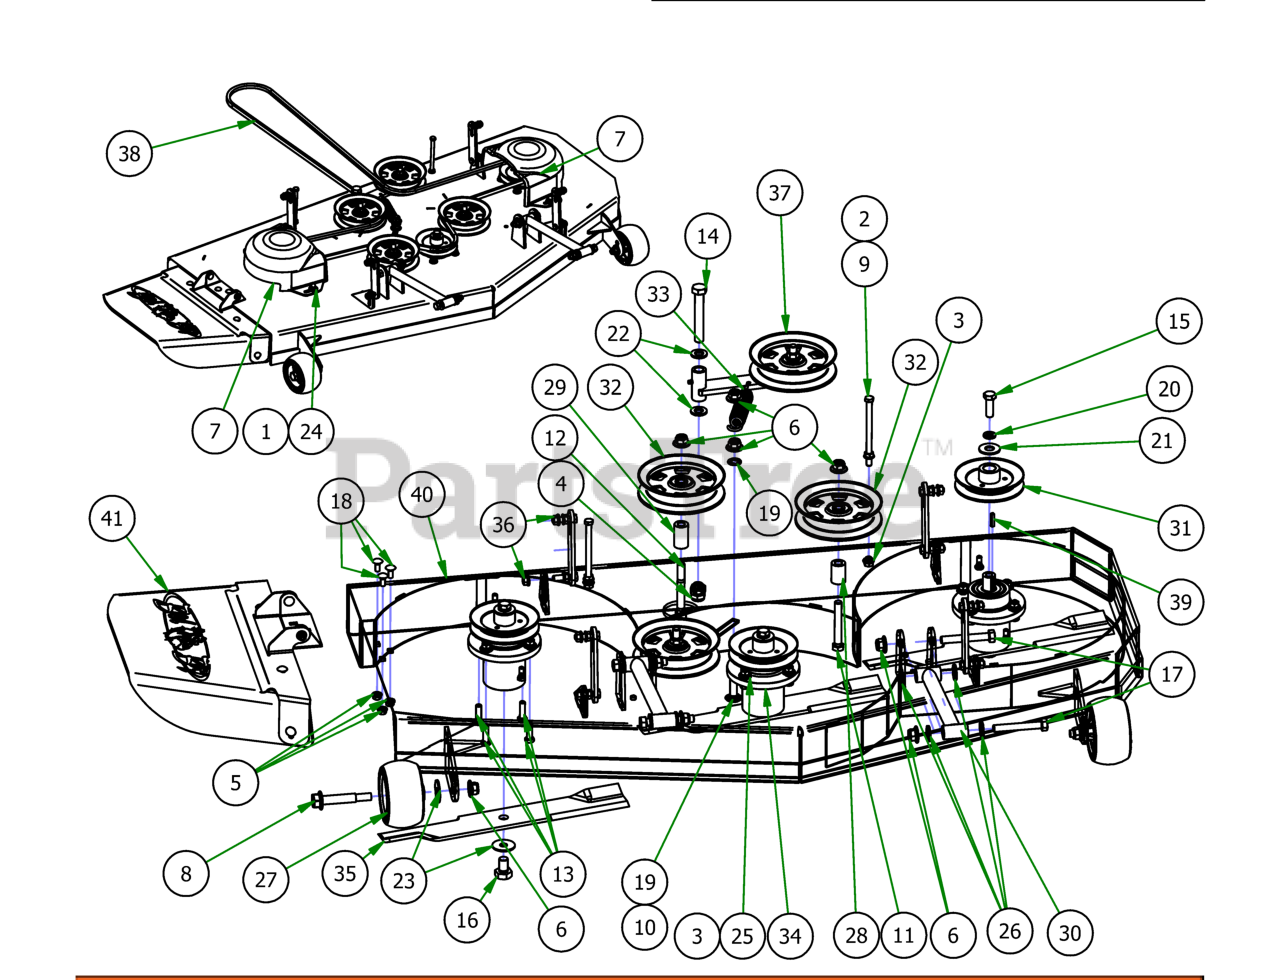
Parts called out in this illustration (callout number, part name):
1	Acorn nut-pulley Cover
2	3/8" Flange Nut
3	3/8-16 NYLON INSERT FLANGE LOCKNUT (GR.F) ZINC
4	5/8-11 Nylon Insert Jam Half Nut
5	5/16-18 NYLON INSERT FLANGE LOCKNUT ZINC
6	1/2-13 NYLON INSERT FLANGE LOCKNUT ZINC
7	Pulley Cover
8	Deck Wheel Bolt
9	3/8-16 X 5-1/4 HEX CAP SCREW (GR.5) ZINC
10	1/2 x 2" Carriage Bolt
11	1/2 x 3 1/2 Flange Bolt Grade 8
12	1/2" x 4" Bolt (Grade 8)
13	3/8" x 1 1/4" Hex Bolt
14	5/8" x 4" Hex Bolt
15	1/2"-20 x 1 1/2 - Grade 5 Fine Thread Bolt
16	5/8" x 1 1/2" Grade 8 Hex Bolt (Fine)
17	1/2-13 x 3 1/2 GR 5 Hex Bolt
18	5/16-18 x 3/4 Carriage Bolt
19	.517 Square Hole Round Washer
20	1/2" Lock Washer
21	5/8'' Flat Washer
22	.630 ID Plastic Washer
23	1/2" Belleville Washer
24	.360 ID Plastic Washer-Black
25	5/16 USS FLAT WASHER (7/8 OD) ZINC
26	.505 Nylon Spacer
27	Deck Wheel
28	.502 ID X .750 OD X 1.500 Long Spacer
29	1 3/4" Pulley Spacer
30	MZ/ZT Deck Locator
31	54 MZ Spindle Pulley
32	5-3/4 Idler Pulley
33	Deck Idler Spring
34	Spindle Assembly-MZ
35	54" Fusion Blade for ZT/Mav/Outlaw/Revolt
36	Deck Hanger Assembly
37	2017 54"/48" Deck Idler Assembly
38	B155.75 Deck Belt
39	3/16 X 1 SQ MACHINERY KEY 1018 STL ZINC
40	2017 54" MZ Magnum Deck
41	MZ Discharge Chute Assembly
